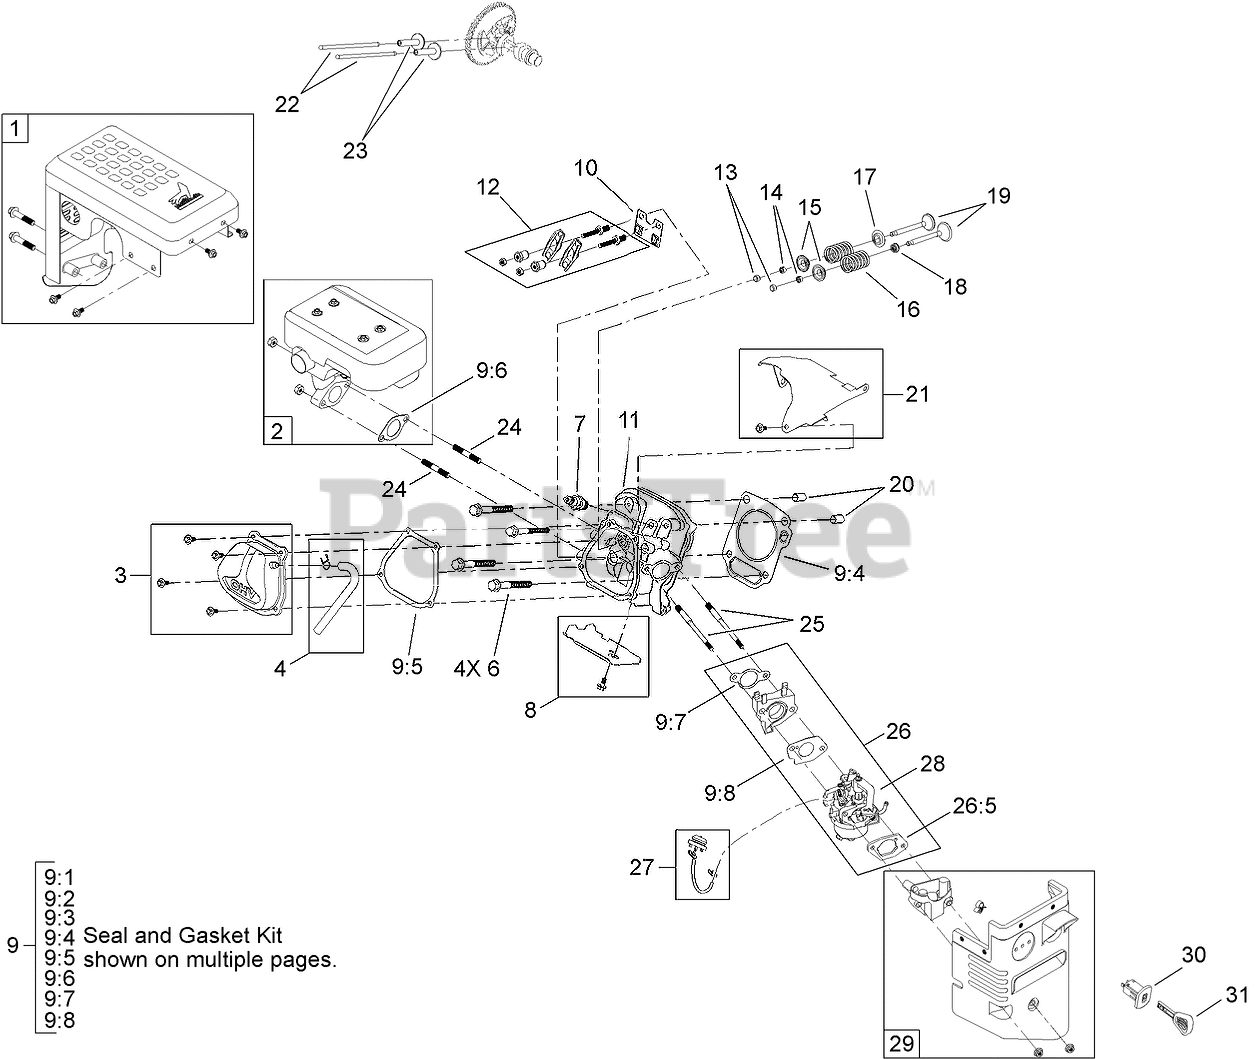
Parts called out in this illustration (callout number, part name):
1	MUFFLER SHIELD KIT
2	MUFFLER KIT
3	VALVE COVER KIT
4	BREATHER TUBE KIT
6	SCREW-HHF
7	PLUG-SPARK
8	LOWER HEAT SHROUD KIT
9	SEAL AND GASKET KIT
9:1	Seal-Oil
9:2	Seal-Oil
9:3	GASKET-COVER, CRANKCASE
9:4	GASKET-HEAD, CYLINDER
9:5	GASKET-COVER, VALVE
9:6	Gasket-Exhaust
9:7	GASKET-CARBURETOR
9:8	GASKET-CARBURETOR
10	PLATE-GUIDE, PUSH ROD
11	HEAD-CYLINDER
12	ROCKER ARM ASM
13	ROTATOR-VALVE
14	KEEPER-VALVE
15	RETAINER-SPRING, VALVE
16	SPRING-VALVE
17	SEAT-SPRING, VALVE
18	SEAL-STEM, VALVE
19	VALVE KIT
20	PIN-DOWEL
21	UPPER HEAT SHROUD KIT
22	ROD-PUSH
23	LIFTER-VALVE
24	STUD-MOUNT, MUFFLER
25	STUD-MOUNT, CARBURETOR
26	COMPLETE CARB SERVICE KIT
26:5	GASKET-COATED, RUBBER
27	PRIMER KIT
28	CARB REPAIR KIT WITH GASKETS
29	HEATER BOX KIT
30	SWITCH-KEY
